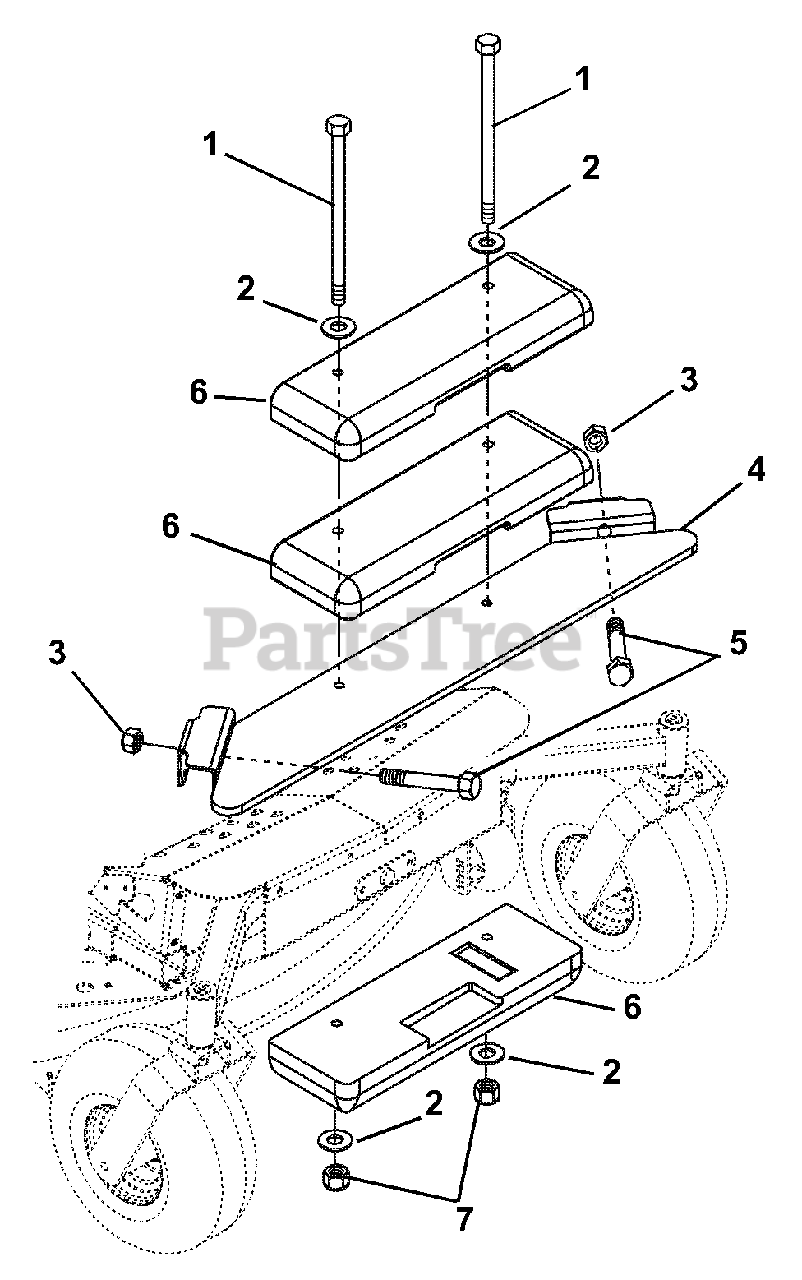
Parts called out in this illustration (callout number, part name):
1	Bolt-Hex .50-13 x 7.50 Grade 5
2	Washer-Flat-Steel .51 x 1.00 x .062
3	Nut-Locking-Nylon .38-16
4	Weldment-260Z Counter Weight
5	Bolt-Hex .38-16 x 3.00 Grade 5
6	Counterweight
7	Nut-Locking-Center .50-13
